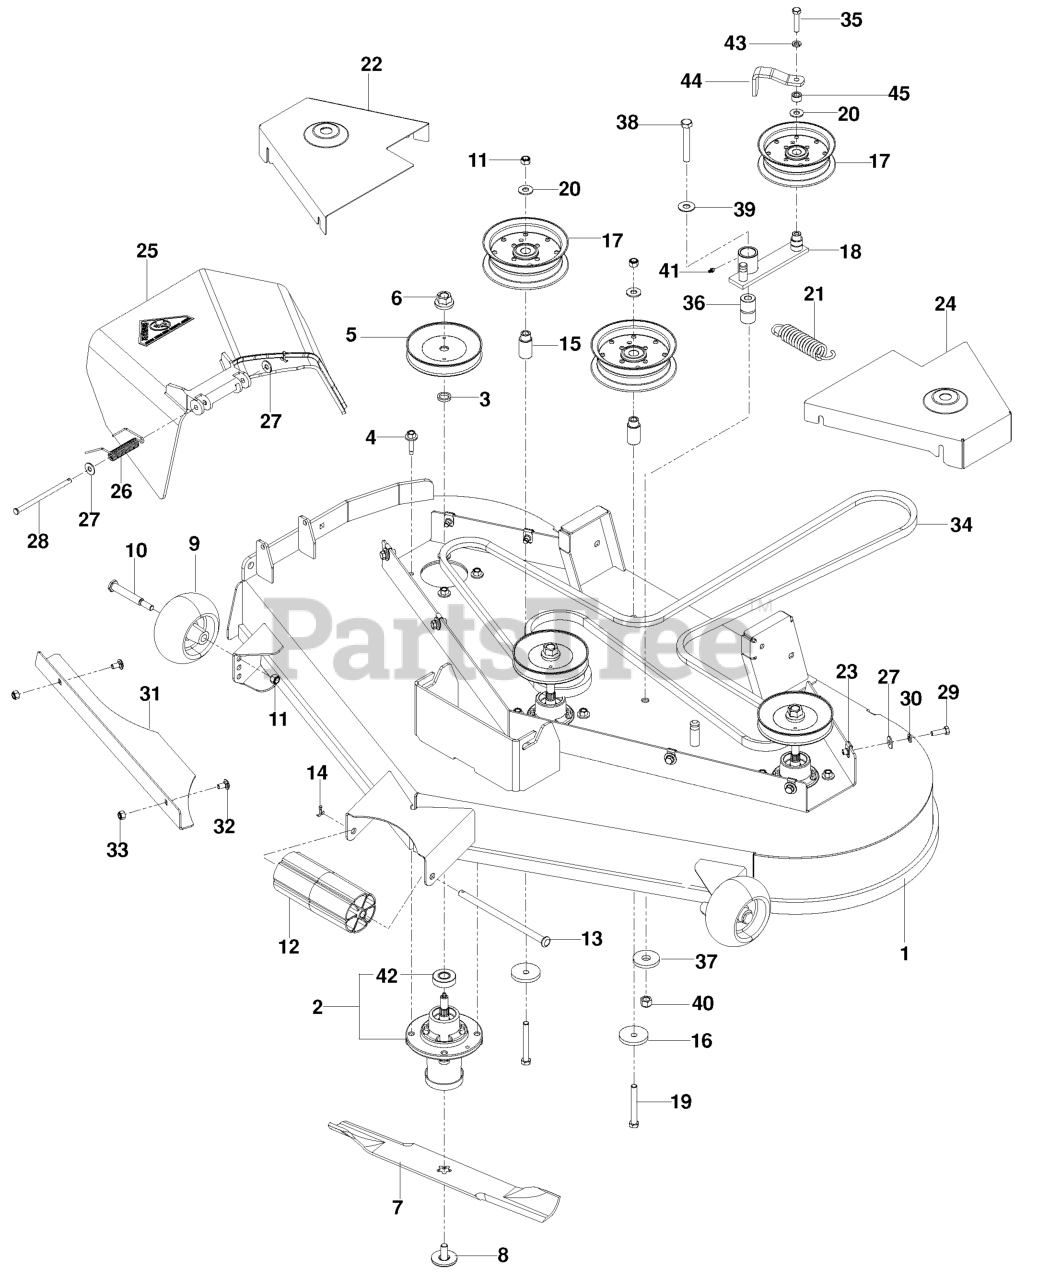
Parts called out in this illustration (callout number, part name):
1	DECK.SVC.W/DECALS.EZ52
2	MANDREL.DECK.ASSEMBLY
3	WASHER-SPACER
4	WASHER HEAD SCREW
5	PULLEY
6	LOCKNUT - 9/16
7	BLADE, 18"
8	BLADE BOLT ASSY-7/16" TB REPL
9	GAUGE WHEEL
10	SHOULDER BOLT 1/2X2-5/8 ZD SPE
11	NUT 3/8-16 NYLOC
12	NOSE ROLLER 48"
13	NOSE ROLLER ROD
14	RP_COTTER PIN 1/8 X 3/4
15	IDLER BUSHING
16	SPINDLE WASHER
17	PULLEY, IDLER
18	PULLEY - IDLER, NYLON
19	HCS 3/8C X 3
20	WASHER 3/8 FLAT
22	BELT SHIELD, RIGHT 52, ORG
23	U-CLIP 5/16-18 NUT RETAINER
24	BELT SHIELD, LEFT 52, ORG
25	DISCHARGE CHUTE 52"
26	SPRING - TORSION
27	WASHER 5/16 FLAT
28	PIN-CLEVIS 5/16 DIA X 5.19 ZD
29	HCS 5/16C X 1
30	WASHER.LOCK.HVY.HLCL.SPR.5/16
31	CONFINEMENT PLATE, 52"
32	CARRIAGE BOLT 5/16C X 5/8"
33	NUT 5/16 NYLOC
34	BELT, DECK
35	HCS 3/8-16 X 1 3/4 GR5
36	PIVOT BUSHING
37	WASHER, SUPPORT
38	HCS 1/2C X 3 1/4
39	WASHER 1/2 FLAT
40	NUT 1/2-13 HEX NYLOC ZD
41	ZERK
42	BEARING, BALL
43	SLW 3/8 STD
44	GUIDE, BELT
